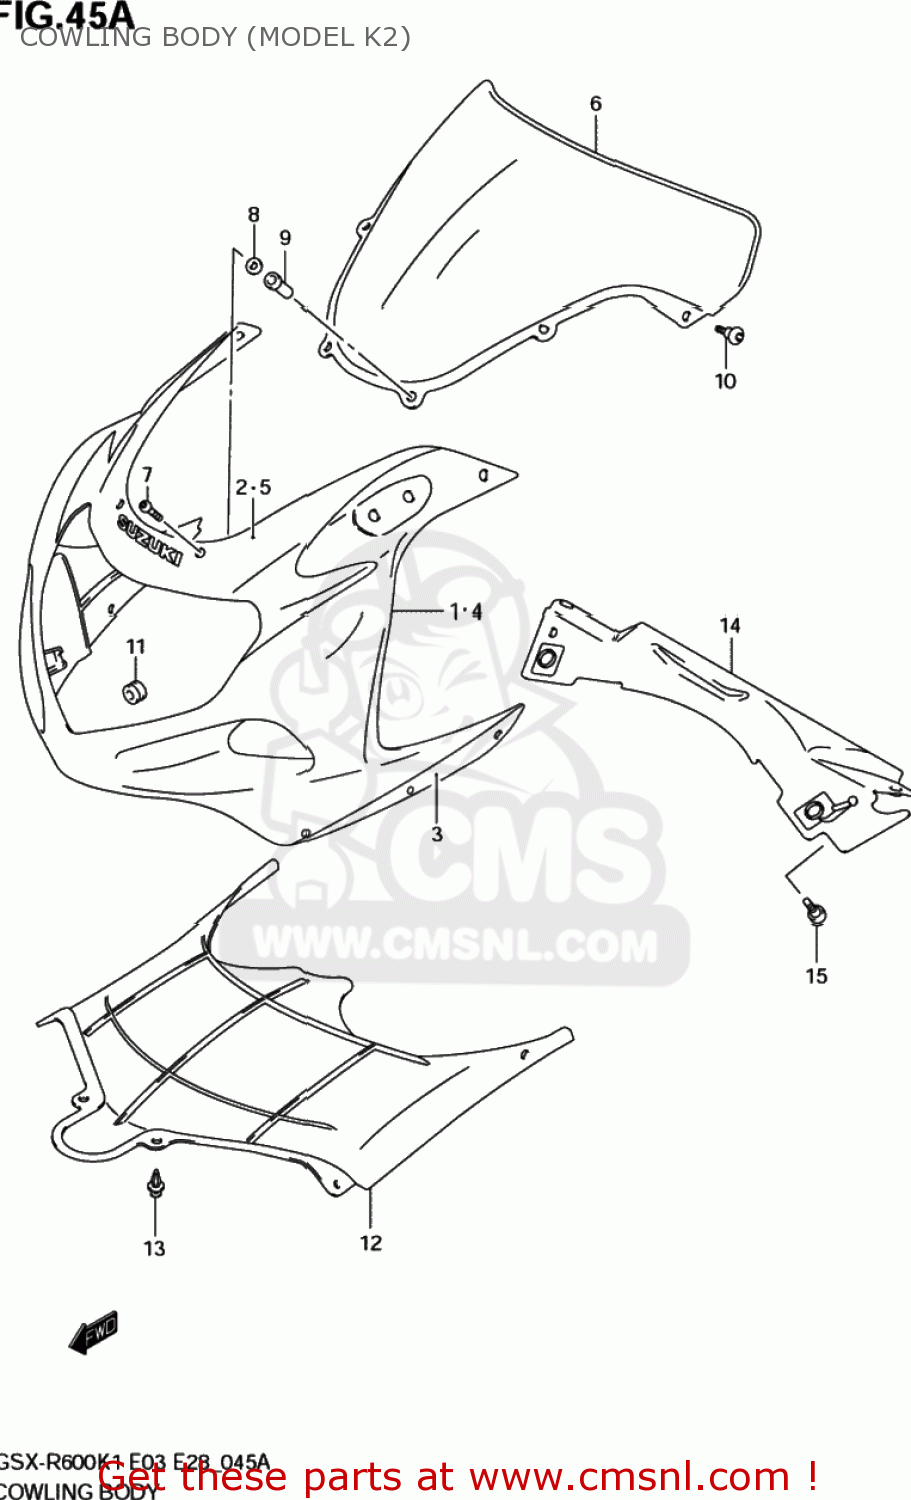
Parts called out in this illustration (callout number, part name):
1	COWLING,BODY(BLUE)
2	TAPE,COWL BODY FR
3	TAPE SET,COWL BODY SIDE
4	COWLING,BODY(BLUE)
5	TAPE,COWL BODY FR
6	WINDSCREEN
7	SCREW(5X14)
8	WASHER
9	NUT
10	SCREW(5X16)
11	CUSHION
12	COVER,BODY COWLING
13	CLIP(BLACK)
14	COVER,COWLING FR LWR
15	BOLT(5X16)
